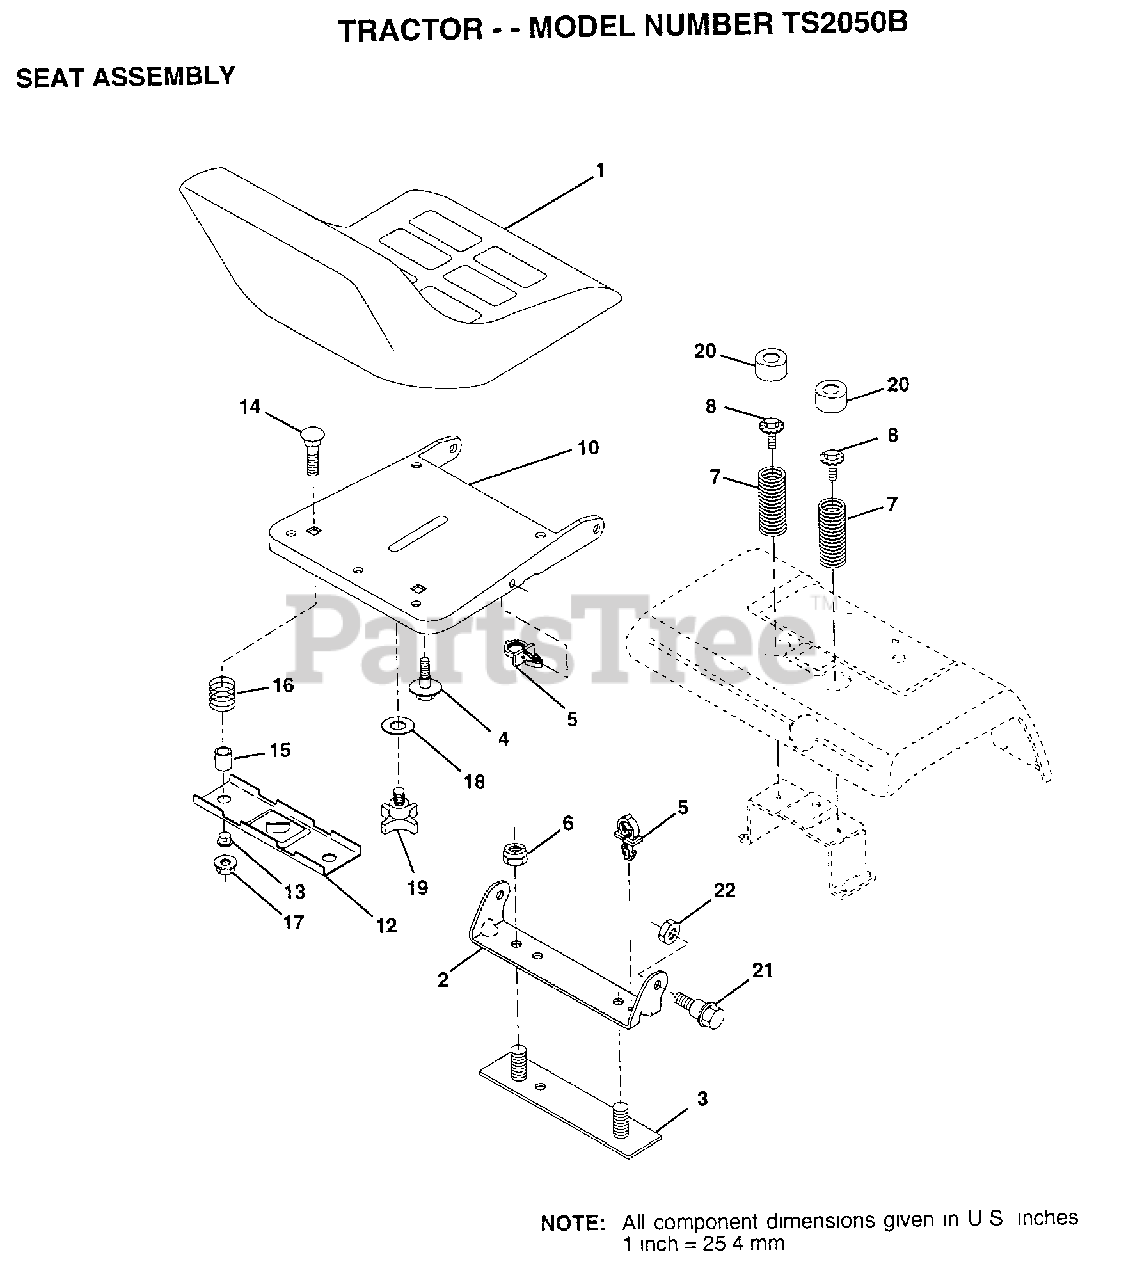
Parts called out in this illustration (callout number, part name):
2	BRACKET PVT SEAT
3	STRAP ASM FENDER
4	"BOLT,SHOULDER"
5	CLIP.PUSH-IN.HING
7	SPRING COMPRESSIO
8	BOLT.5/16-18.UNC
12	BRKT SWITCH
13	BUSHING
15	SPACER SPLIT
16	SPRING COMPRESSED
18	WASHER
19	"KNOB 1/2"" YT"
20	CAP SPRING
21	"BOLT,SHOULDER"
